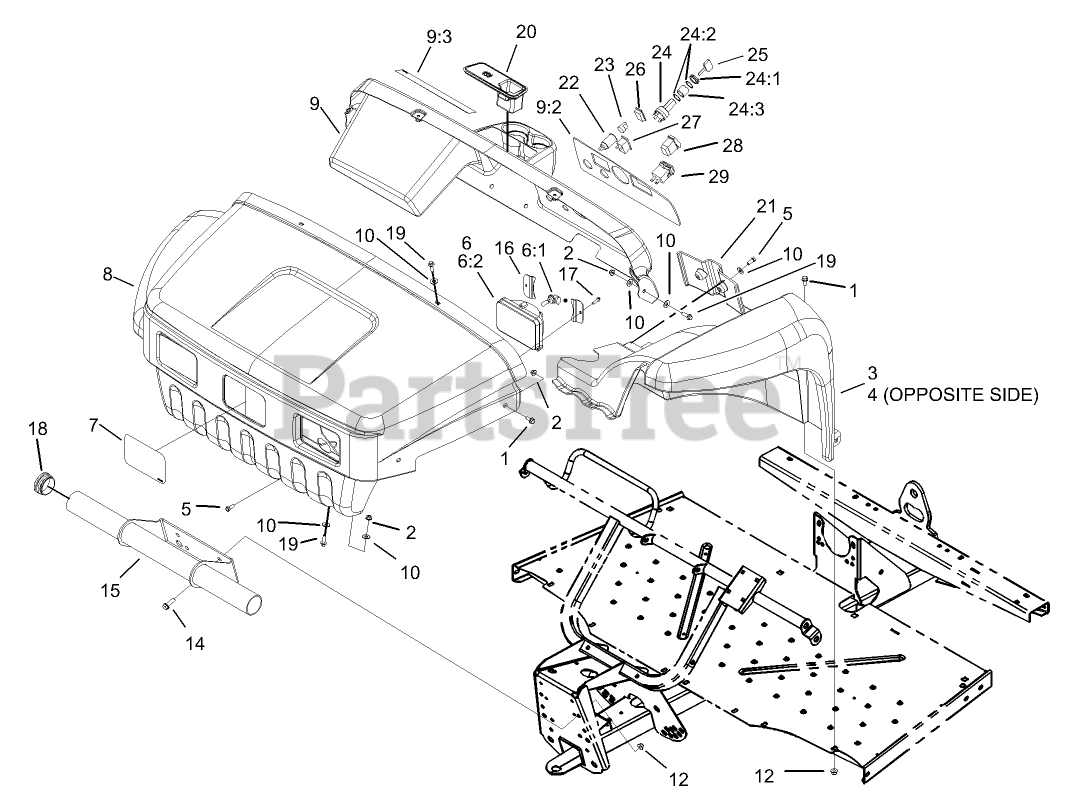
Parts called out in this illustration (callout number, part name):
1	SCREW-HHF
2	NUT-HF, NI
3	LH FENDER ASM
4	RH FENDER ASM
6	HEADLIGHT
6:1	LAMP-12 VOLT
7	DECAL
9:2	DECAL-WARNING, DASH
10	WASHER-FLAT
12	NUT-HF, NI
15	BUMPER-TUBE
16	BRACKET-HEADLIGHT
17	SCREW-HWH
18	CAP-END
19	SCREW-HHF
20	PLUG-RUBBER
21	COVER-CHANNEL
22	POINT-POWER
24	SWITCH-IGNITION
24:1	NUT-SWITCH, PLASTIC
24:2	WASHER-LOCK, INTERNAL
24:3	SPACER-SWITCH
25	KEY-IGNITION
26	PLUG-HOLE
27	INDICATOR-LIGHT, LOW-OIL PRESSURE
28	SWITCH
29	HOURMETER
